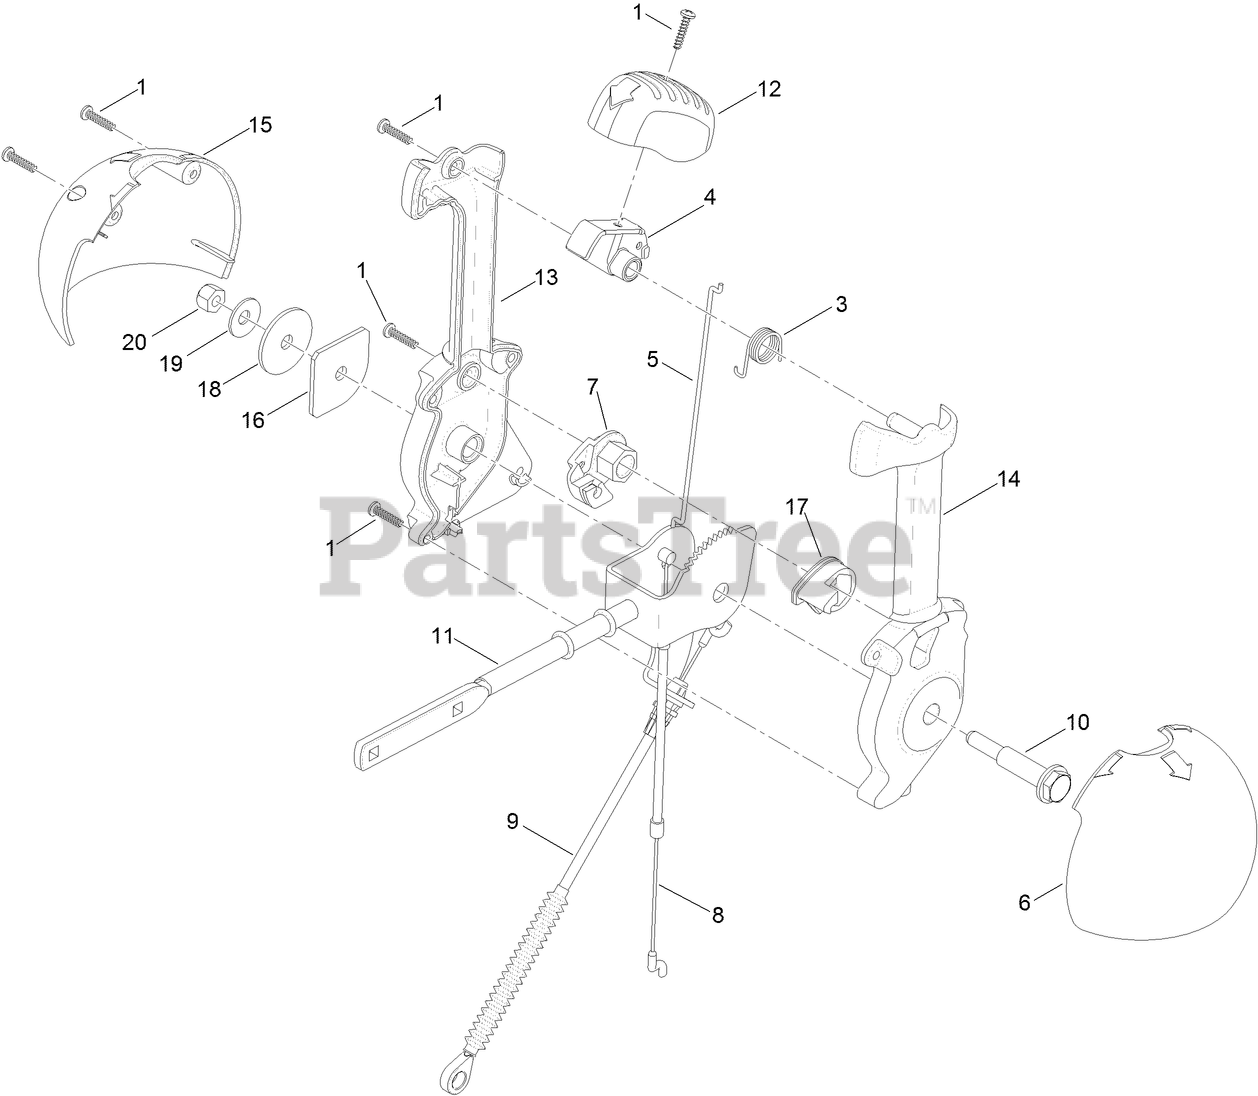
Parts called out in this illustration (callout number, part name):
1	SCREW-PPH
3	SPRING-TORSION
4	TRIGGER-LATCH
5	LINK-LATCH
6	COVER-LEVER, CHUTE (LH)
7	LEVER-CABLE, DEFLECTOR
8	CABLE-RELEASE, CHUTE
9	CABLE-CONTROL, DEFLECTOR
10	SCREW-SHOULDER
12	CAP-LEVER
13	LEVER-CONTROL, CHUTE (RH)
14	LEVER-CONTROL, CHUTE (LH)
15	COVER-LEVER, CHUTE (RH)
17	PAWL-LATCH
18	WASHER-NYLON
19	WASHER-BELLEVILLE
20	NUT-LOCK, NI
